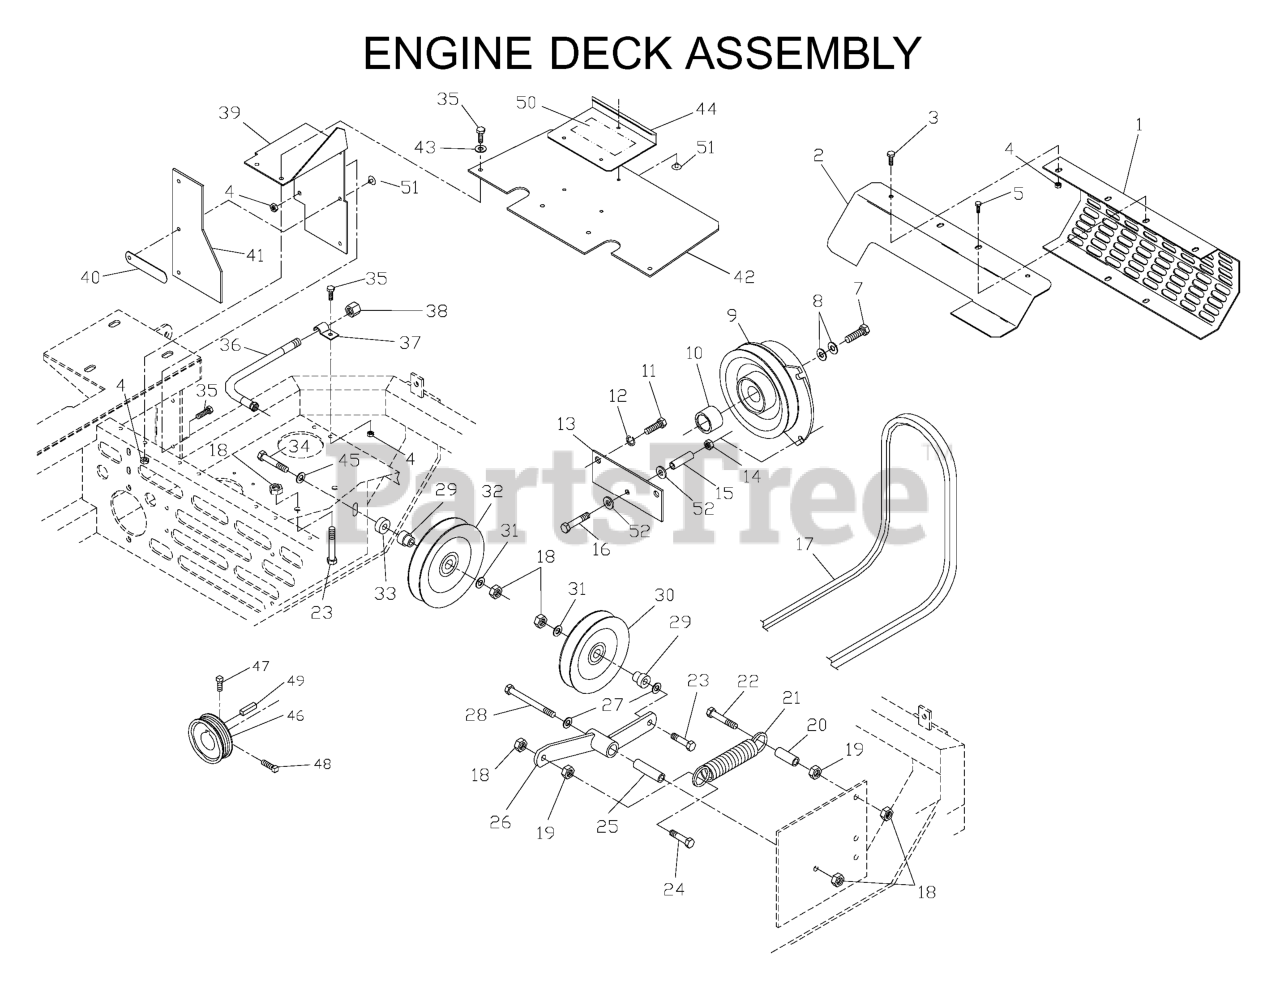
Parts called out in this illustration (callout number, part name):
1	MUFFLER SHIELD
2	HEAT DEFLECTOR
3	HCS 1/4C X 5/8
4	NUT 1/4C CENTERLOCK
5	HEX CAP SCREW M6 X 1MM X 10MM
7	BOLT 7/16F X 2 1/2
8	WASHER, 7/16 DISC SPRING
9	CLUTCH/BRAKE-GEN I
11	HCS 7/16-14 X 1 GR 5 ZD
12	WASHER 7/16 LOCK
13	CLUTCH STOP PLATE
14	NUT 5/16C CENTERLOCK
16	BOLT 5/16C X 3 1/4 HEX TAP
17	BELT, MULE DRIVE
18	NUT 3/8C CENTERBLOCK
19	NUT 3/8C WHIZ
22	HCS 3/8C X 2 1/2
23	HCS 3/8-16 X 1 3/4 GR5
24	HCS 3/8C X 2 1/4
26	ARM WELDMENT
27	WASHER 3/8 FLAT
28	HCS 3/8C X 3
29	SHOULDER BUSHING
30	IDLER PULLEY
31	WASHER 3/8 SAE FLAT
32	IDLER PULLEY
34	SCREW 3/8C X 2 3/4 HEX CAP
35	HCS 1/4C X 3/4 HCS
36	OIL DRAIN HOSE
39	ENGINE BAFFLE, LEFT
40	SHIELD CLIP
41	HEAT SHIELD
42	ENGINE SHIELD/COMPLETE
43	WASHER 1/4 FLAT
44	LIFT SHIELD
45	WASHER, 3/8 DISC SPRING SPEC
46	ENGINE PULLEY
47	SCREW 5/16C X 5/8 SQ HEAD
48	SCREW, HEAD SET 5/16C X 3/4 SQ
49	KEY, 1/4 SQ X 1 1/4
50	DECAL, DANGER
51	RIVET E/16 X 1/4 LG FLG
52	WASHER 5/16 FLAT
539102752	ENGINE BAFFLE, RIGHT
